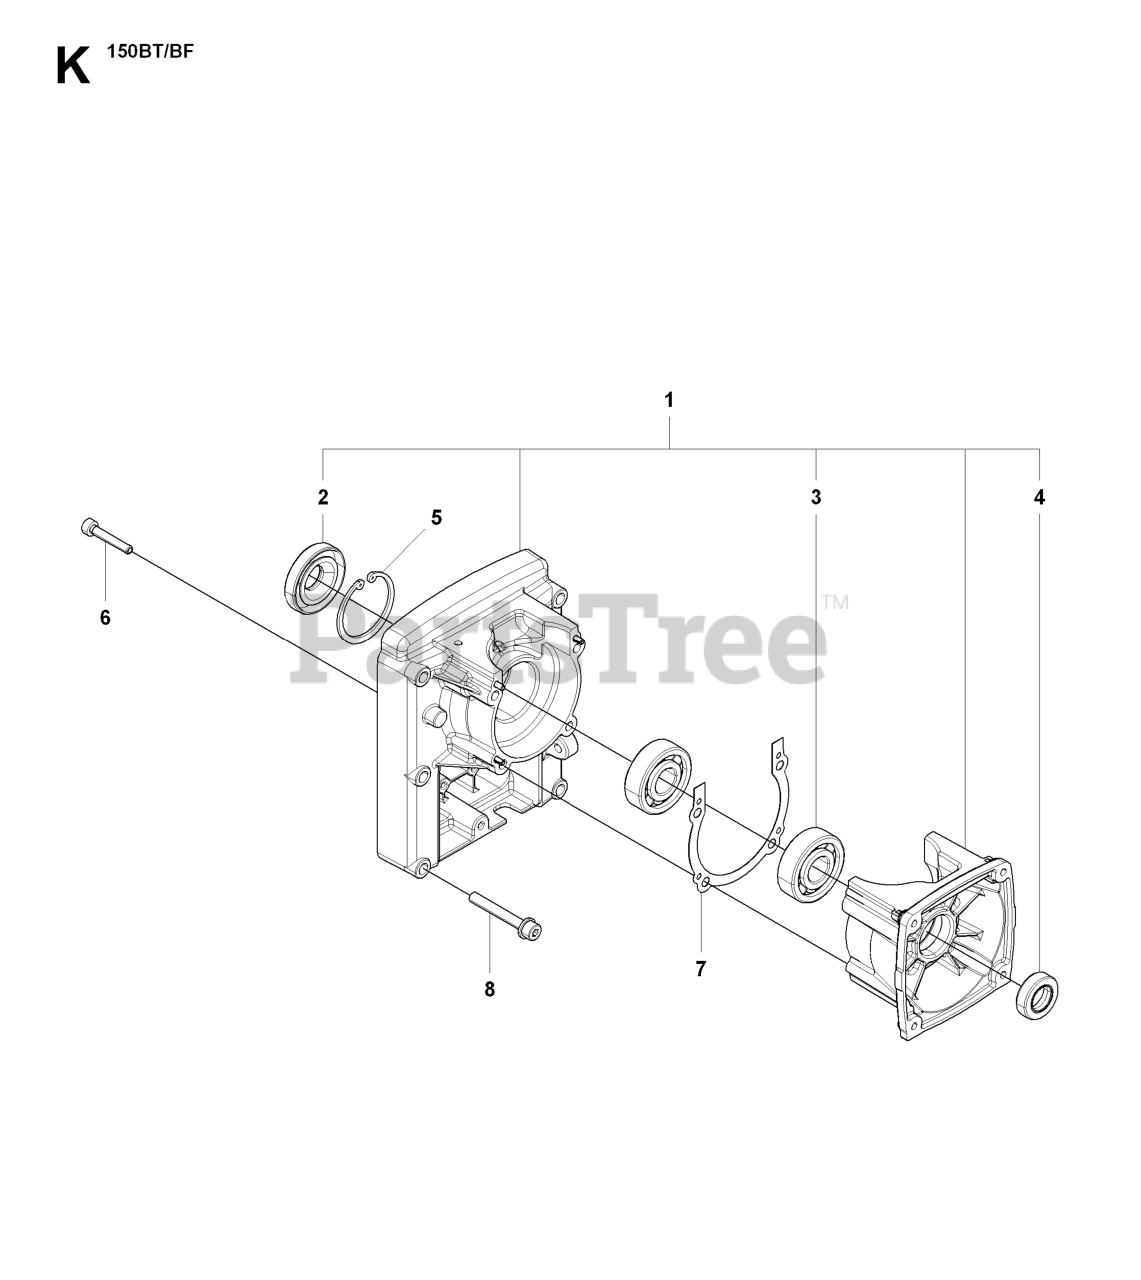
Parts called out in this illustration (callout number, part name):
3	BEARING
6	BOLT
8	BOLT
